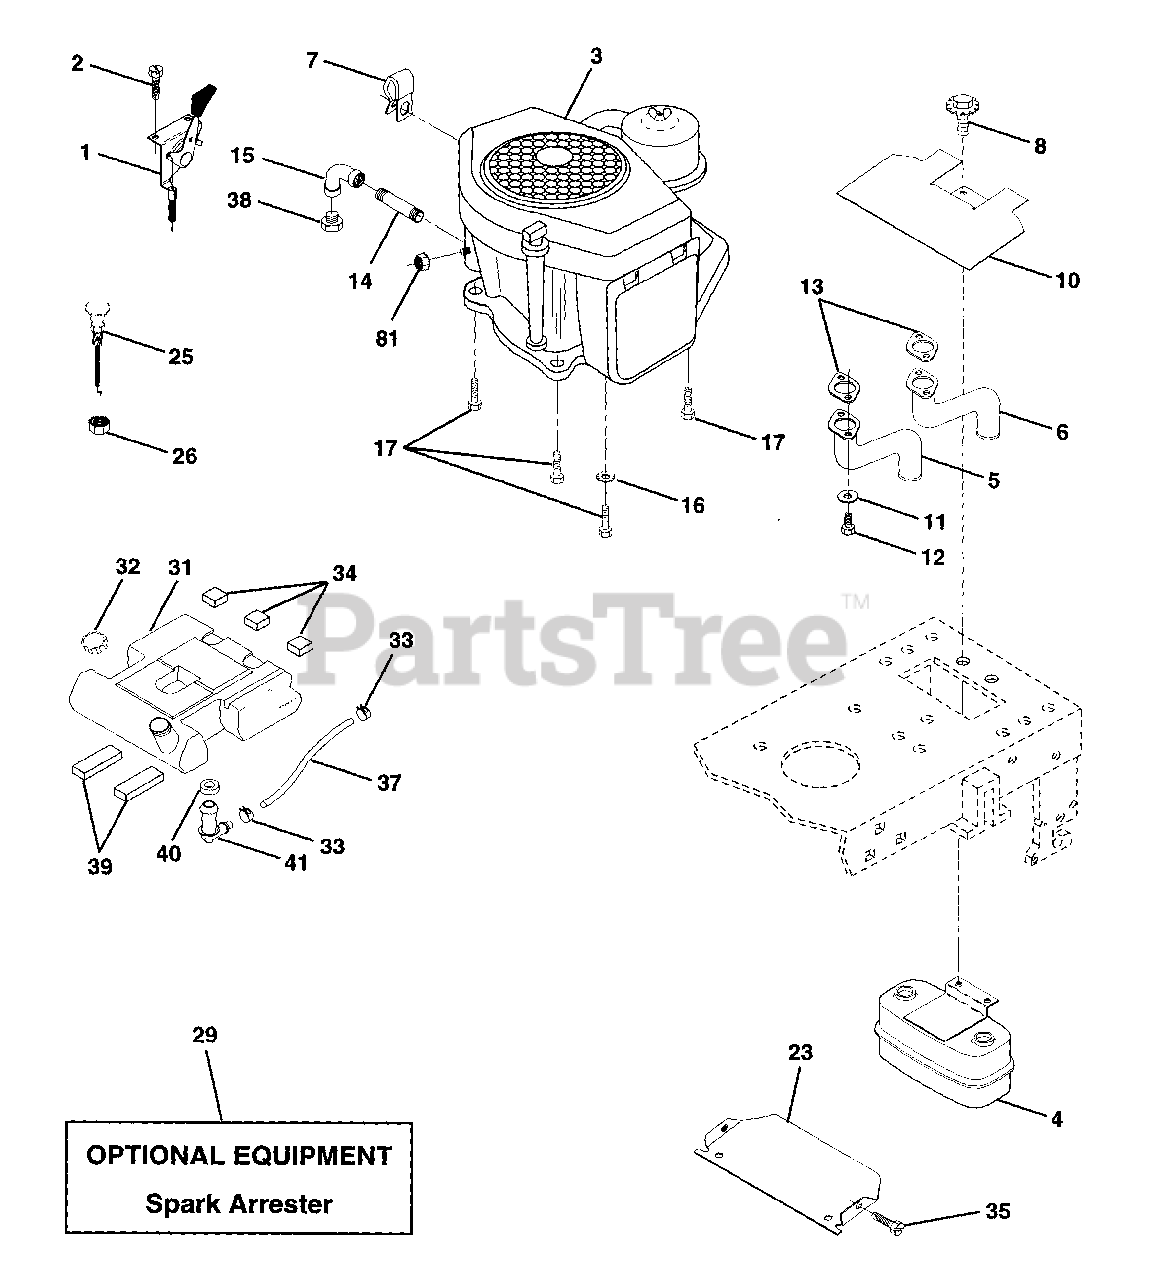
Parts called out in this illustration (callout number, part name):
1	Control Throt Flg 180 LH
2	Screw Hex Thd Cut 1/4-20 x 5/8 T
4	Muffler Asm Twin Lo-Tone
5	Pipe Exhaust CV18/20 LH
6	Pipe Exhaust CV18/20 RH
7	Clip, Fuel Line
8	Bolt 5/16-18unc x 3/4 W/Sems
10	Shield Heat Muffler CV18/20
13	Muffler Gasket
14	Nipple Pipe 3/8 Npt X 4-1/2"
15	Elbow Std 90 Degree 3/8-18 Npt
16	Washer Lock Ext Tooth 3/8
17	Screw Thdrol 3/8-16 x 1-1/2
23	Shield Browning
25	Choke Control 37"
26	Nut, Keps 3/8-24 Unf
29	Kit Spark Arrestor (Flat Scrn)
31	Tank Fuel 3 50 Rear
32	Cap Asm Fuel Top N/Lany Vented
33	Clamp Hose Blk
34	Pad, Spacer
35	Screw Thdrol 5/16-18 x 3/4
37	Line Fuel 7.5
38	Plug Oil Drain
39	Pad, Idler
40	Bushing
41	Stem Tank Fuel
81	Nut Flange 1/4-20 Starter Nut
